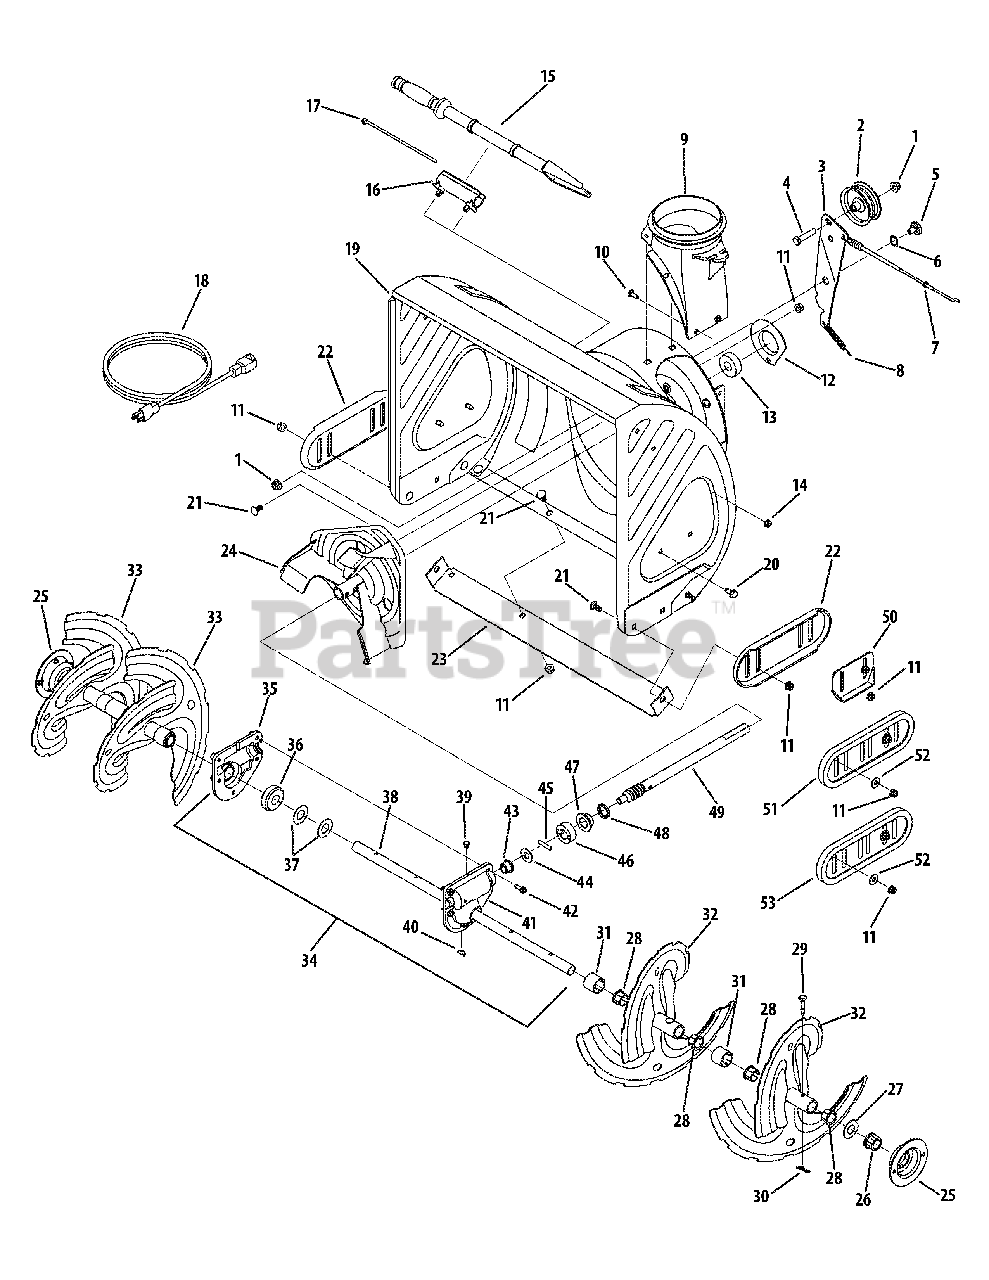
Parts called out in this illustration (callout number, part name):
1	Flange Lock Nut, 3/8 -16
2	Idler Pulley
4	Hex Bolt, 3/8-16 x 1.75
5	Shoulder Screw, .625 x .17 x 3/8-16
6	Wave Washer, .625 x .885 x .015
7	Clutch Cable
8	Extension Spring, .38 OD x 3.6
9	Chute Adapter, 5.0
10	Carriage Screw, 1/4-20 x .75
11	Flange Lock Nut, 5/16-18
12	Bearing Housing
13	Ball Bearing, .75 ID x 1.85 OD
14	Flange Lock Nut, 1/4-20
15	Cleanout Tool
16	Cleanout Tool Mount
17	Cable Tie, 3/16 x .05 x 7.4
18	Extension Cord, 3-Prong
20	Hex Washer Screw, 5/16-18 x .750
21	Carriage Bolt, 5/16-18 x .750
26	Hex Flange Bearing
27	Flat Washer, .76 x 1.49 x .06
28	Flange Bushing .800 ID x .910 OD
30	Bow-Tie Cotter Pin
31	Spacer, 1.25 OD x .75 ID x 1.00
34	Gearbox Assembly, 26"
35	Housing Assembly, RH
36	Worm Gear, 2OT
37	Flat Washer, .760 ID x 1.50 OD
38	Auger Axle, 26"
39	Plug, 1/4 x .437
40	Hi-Pro Key, 3/16 x 5/8
41	Housing Assembly, LH
42	Hex Washer Screw, 1/4-20 x .750
43	Flange Bearing, .50 ID x .75 OD x .59
44	Flat Washer, .51 x 1.12 x .06
45	Dowel Pin, .25 OD x 1.25
46	Thrust Collar, .756 ID x .600
47	Flng. Bearing, .75 ID x 1.00 OD x .59
48	Oil Seal, .75 x 1.131 x .188
49	Worm Shaft, .75 OD
50	Skid Shoe, Standard Steel
50	Screw, Carriage 5/16-18 x .750
50	Nut, Nylon Lock 5/16-18
50	Washer, Flat .349 x .879 x .063
51	Skid Shoe, Polymer Small
51	Standard Polymer Reversible Shoe Kit
51	Screw, Carriage 5/16-18 x .750
51	Nut, Nylon Lock 5/16-18
51	Washer, Flat .349 x .879 x .063
52	Flat Washer, .349 x .879 x .063
53	Deluxe Polymer Skid Shoe
53	Deluxe Polymer Reversible Shoe Kit
53	Screw, Carriage 5/16-18 x .750
53	Nut, Nylon Lock 5/16-18
53	Washer, Flat .349 x .879 x .063
